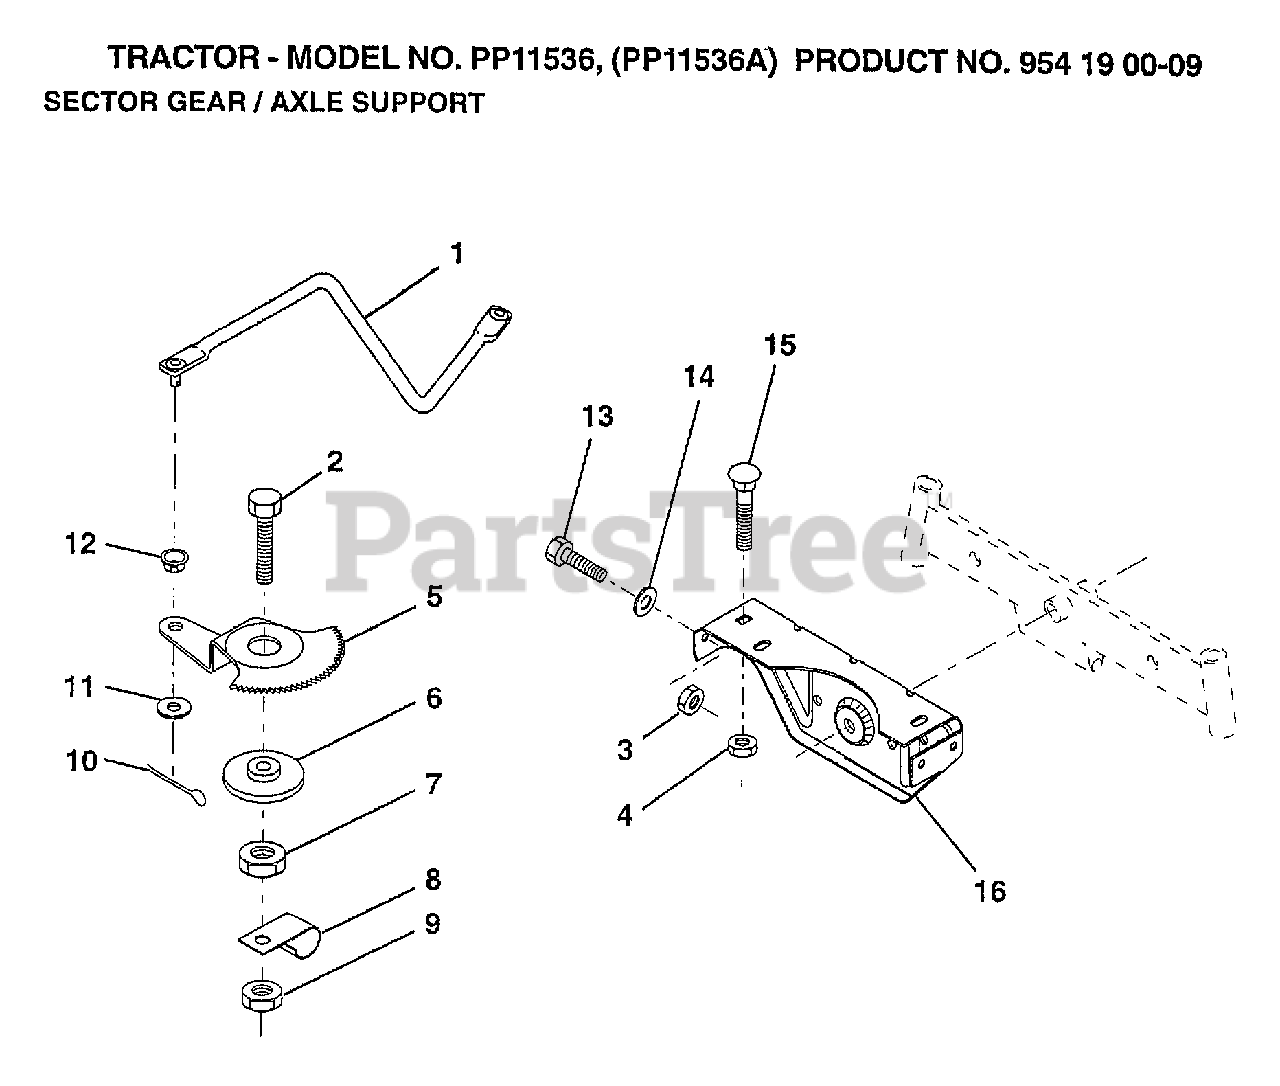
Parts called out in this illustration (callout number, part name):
1	DRAG LINK
2	"BOLT,HEX"
5	GEAR SECTOR
6	BUSHING
7	NUT
8	CLIP INSULATOR
9	NUT LTV
10	COTTER PIN
11	WASHER
12	BUSHING.DRAGLINK
13	BOLT
14	WASHER
15	BOLT
16	SUPT AXLE FRONT
